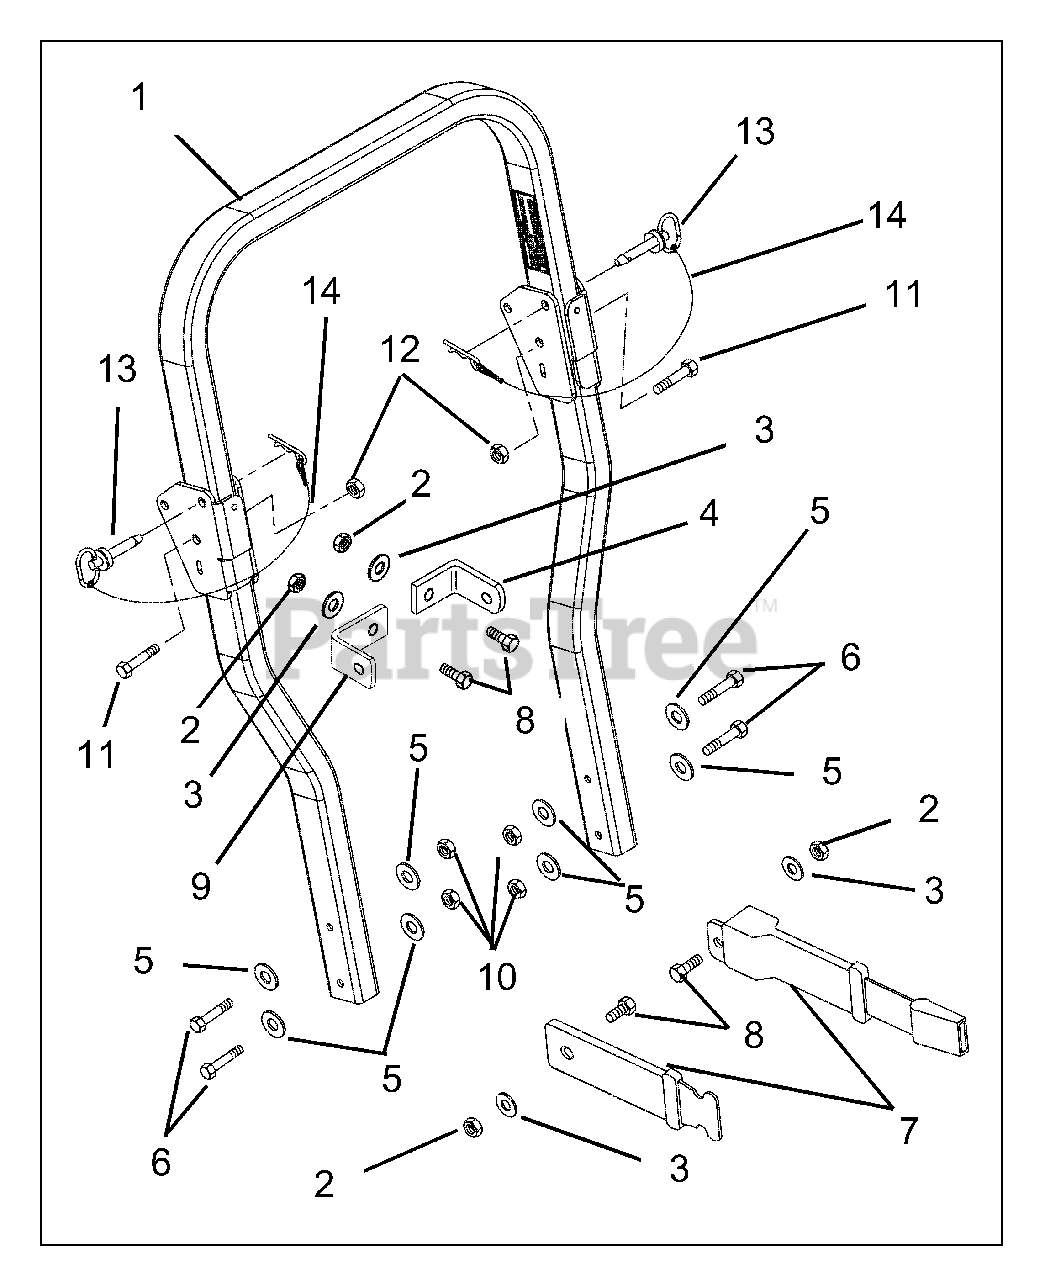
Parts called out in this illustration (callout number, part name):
1	KIT,FOLDABLE ROPS-100 SERIES
2	@NUT-LK-NYL .44-14 YWZC
3	@WSHR-FL-STL.50X1.25X.083 YWZC
4	BRACKET, SEAT BELT MOUNT, LH
5	@WSHR-FL-STL.563X1.38X.109YWZC
6	@BLT-HEX .50-13X3.00 GR5 YWZC
7	ASSY, SEAT BELT
8	@BLT-HEX .44-14X1.00 GR5 YWZC
9	BRACKET, SEAT BELT MOUNT, RH
10	@NUT-LK-NYL .50-13 YWZC
11	@BLT-HEX .50-13X3.25 GR5 YWZC
12	@NUT-LK-CTR .50-13 YWZC
13	HITCH PIN--ROPS BAR
14	LANYARD, U-LOCK NYLON
